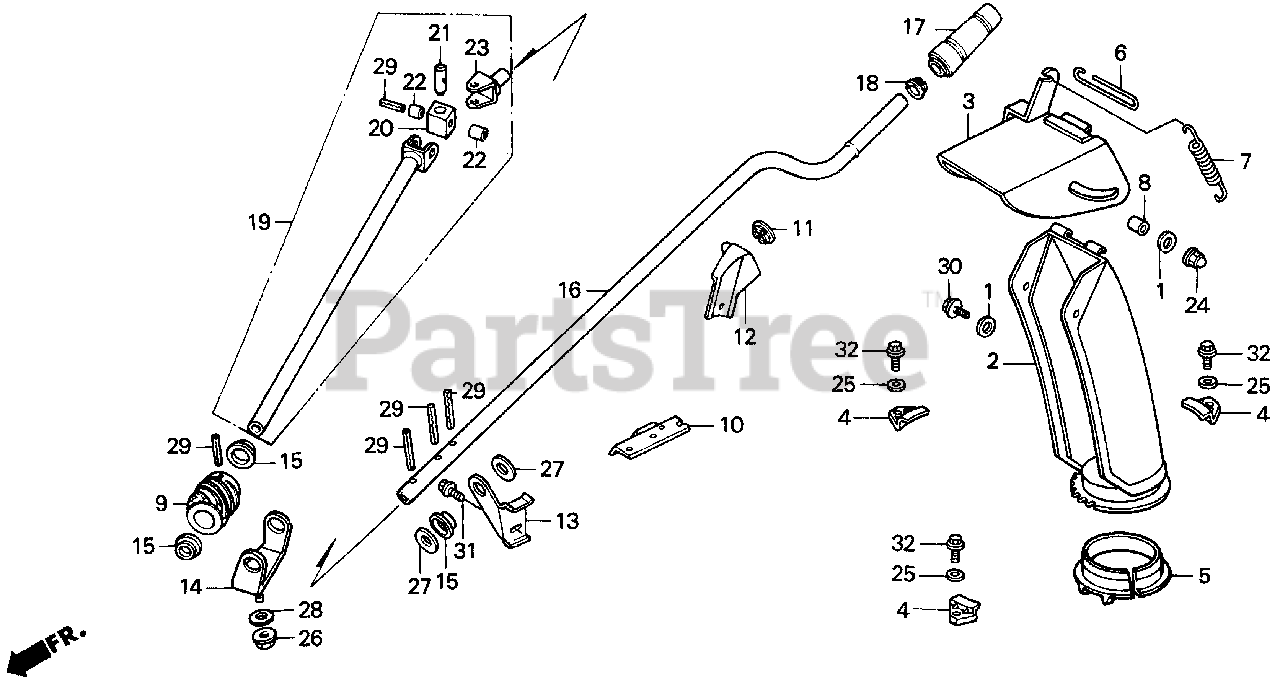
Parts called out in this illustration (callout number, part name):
1	WASHER, ACCELERATOR PEDAL
3	GUIDE, CHUTE (COO)
4	PLATE, CHUTE SETTING
5	BUSH, CHUTE
6	PIN, CHUTE GUIDE
7	SPRING, CHUTE
8	COLLAR, CHUTE GUIDE
9	GEAR, CHUTE DRIVE
10	HOLDER, HANDLE BRACKET
11	BUSH, CHUTE HANDLE
12	BRACKET A, CHUTE HANDLE
13	BRACKET B, CHUTE HANDLE
14	STAY, DRIVE GEAR
15	BUSH, DRIVE GEAR
16	HANDLE, CHUTE (UPPER)
17	GRIP, CHUTE HANDLE
18	BUSH A, CHUTE HANDLE
19	HANDLE, CHUTE (LOWER)
20	PIECE, JOINT
21	PIN A, JOINT
22	PIN B, JOINT
24	NUT, CAP (6MM)
25	WASHER, CHUTE SETTING
26	NUT, FLANGE (8MM)
27	WASHER, PLAIN (16MM)
28	WASHER, PLAIN (8MM)
29	PIN, SPRING (4X28)
30	BOLT, FLANGE (6X12)
31	BOLT, FLANGE (6X14)
32	BOLT, FLANGE (8X12)
